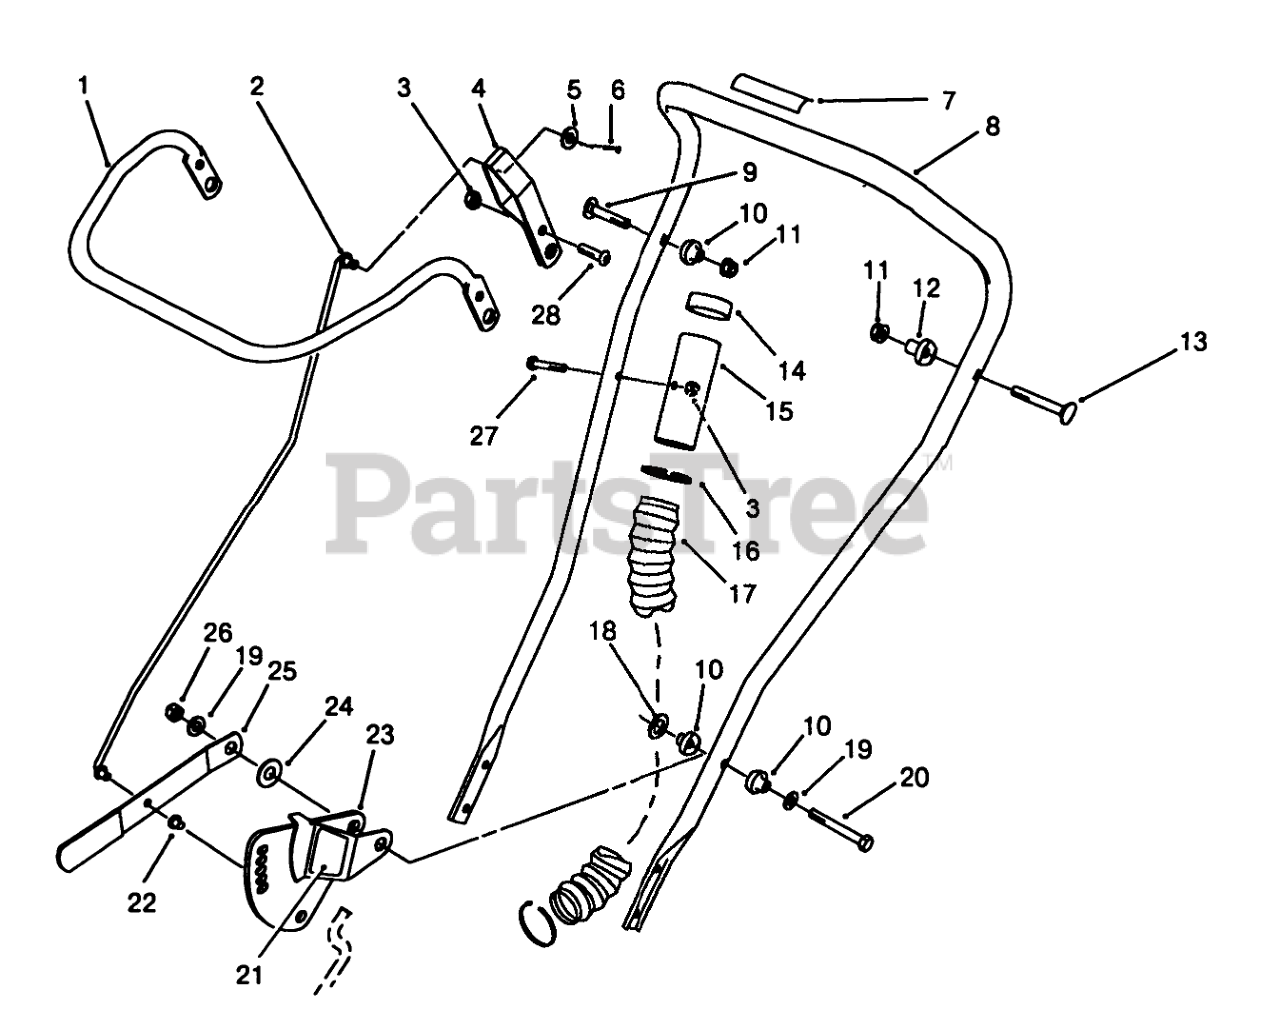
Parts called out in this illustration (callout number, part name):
1	Bar-Control
2	UPPER CONTROL ROD
3	NUT-LOCK, NI
4	CONTROL BAR BRKT.
5	WASHER-FLAT
6	PIN-COTTER
7	DECAL
8	UPPER HANDLE
9	SCREW-HANDLE
10	PIVOT SPACER
11	NUT-LOCK, NI
12	SPACER-SUPPORT
13	5/16-18 X 2 HNDLE SCREW
14	BLACK CAPLUG
15	AIR CLNR HOSE TIP
16	TIE-CABLE
17	AIR CLEANER HOSE
18	WASHER
19	WASHER-PLAIN
20	SCREW-HH
21	DECAL
22	PUSHNUT
23	ADJ.PLATE WA
24	WASHER
25	ADJ.HANDLE
26	NUT-LOCK, NI
27	SCREW-HH
28	SCREW-HSBH
